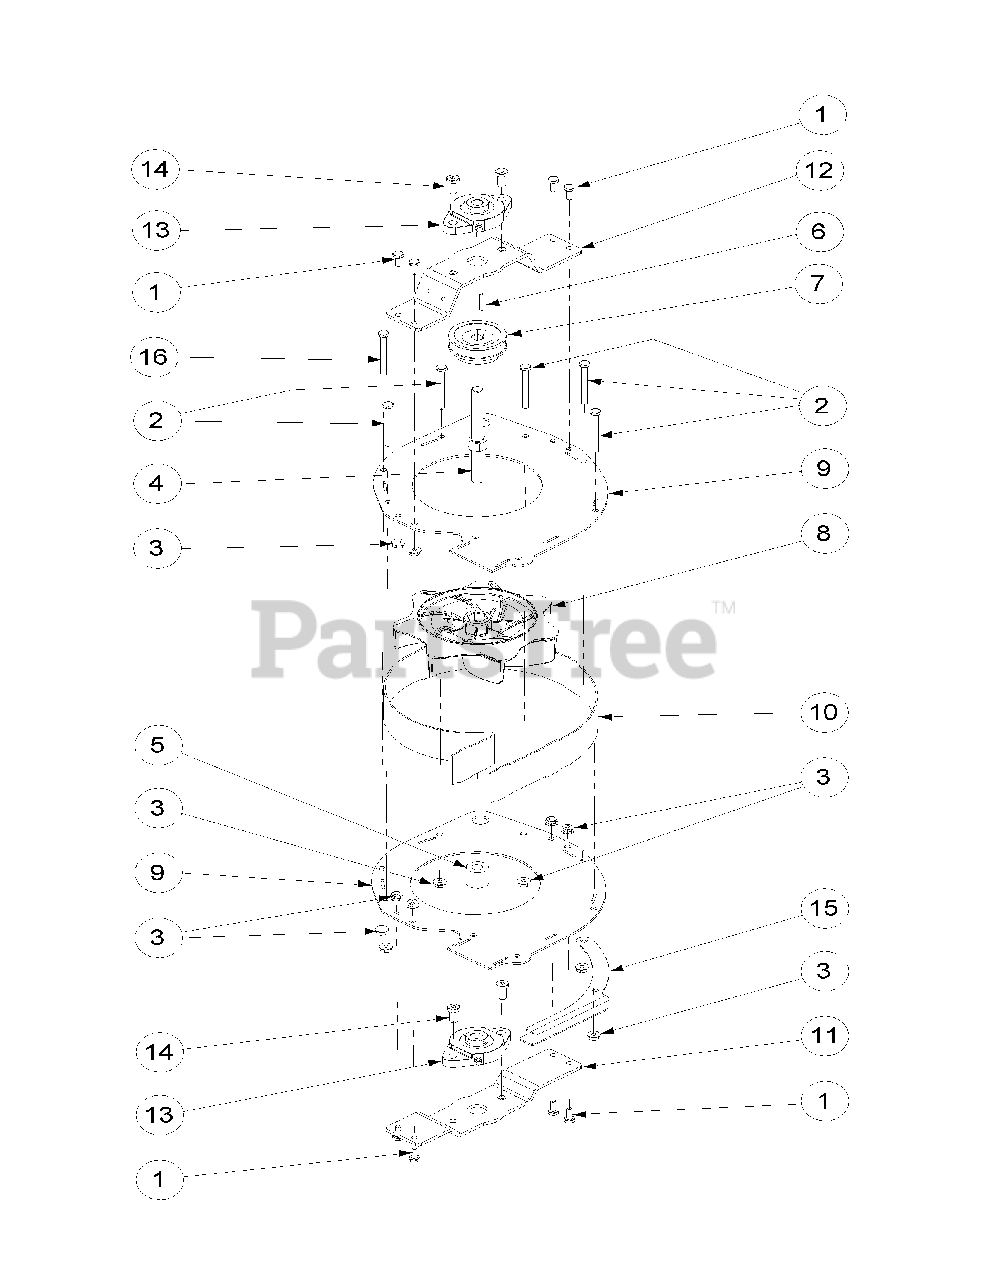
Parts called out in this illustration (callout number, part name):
1	HHCS, 1/4-20 x 0.620
2	HHCS, 1/4-20 x 2.50
3	Hex Nut Flange Lock, 1/4-20
4	Blower Shaft
5	Blower Spacer
6	Key, 1/8 x 1/8 x 1.00
7	Cast Pulley, .500 ID x 2.50 OD
8	Blower Impeller
9	Blower Housing Cover
10	Blower Housing Band
11	Bottom Bearing Mounting Plate
12	Top Bearing Mounting Plate
13	Flange Bearing
14	Socket Head Screw, 3/8-16 x .75
15	Guard Deflector
16	HHCS, 1/4-20 x 2.75
